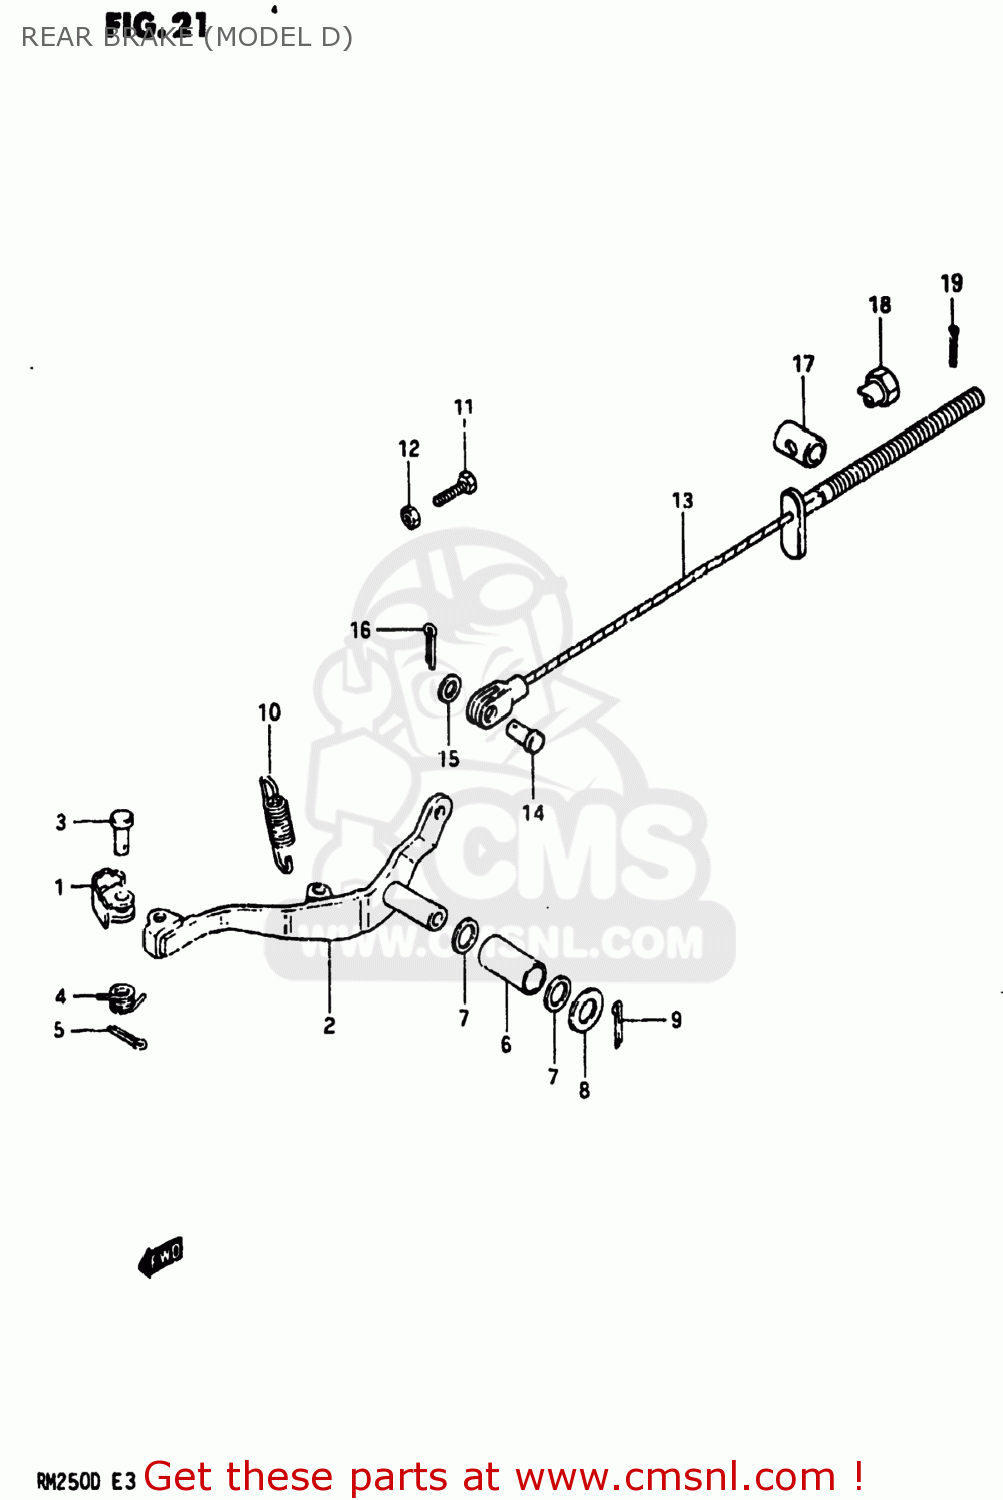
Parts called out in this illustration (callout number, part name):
1	PEDAL,BRAKE
2	ARM,BRAKE PEDAL
3	PIN
4	SPRING
5	PIN
6	BUSHING
7	O RING(D:2.2,ID:11.8)
8	WASHER
9	PIN 30X20
10	SPRING
11	SCREW(6X23)
12	NUT
13	CABLE,RR BRAKE
14	PIN(L:17.5)
15	WASHER
16	PIN 20X20
17	PIN
18	NUT (6MM)
19	PIN
